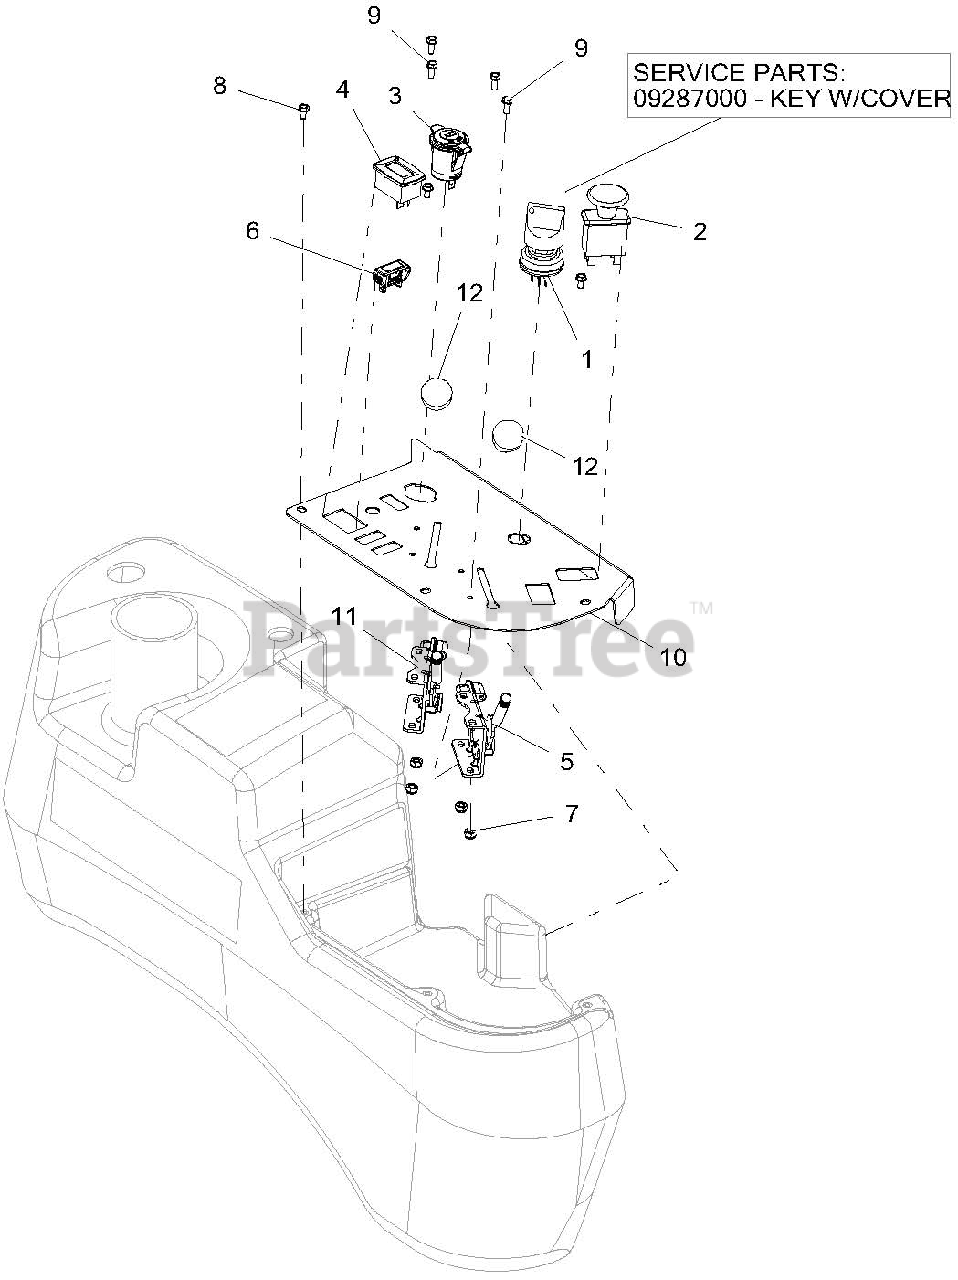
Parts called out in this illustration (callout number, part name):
1	SWITCH, IGNITION
1	KEY W/COVER
2	SWITCH, CLUTCH
3	PORT, 12 VOLT POWER
4	METER, HOUR W/MAINTENANCE
5	CABLE, THROTTLE 53"
6	LIGHT, INDICATOR
7	NUT-LK-NYL #10-24 YWZC
8	SCR-MCH 10-24X.38 HWHSTAINLESS
9	@SCR-MCH 10-24X.50 HWH YWZC
10	PANEL, CONTROL
11	CABLE, PRO-CONTROL CHOKE
12	KNOB, CONTROL BLACK .38-16X.50
